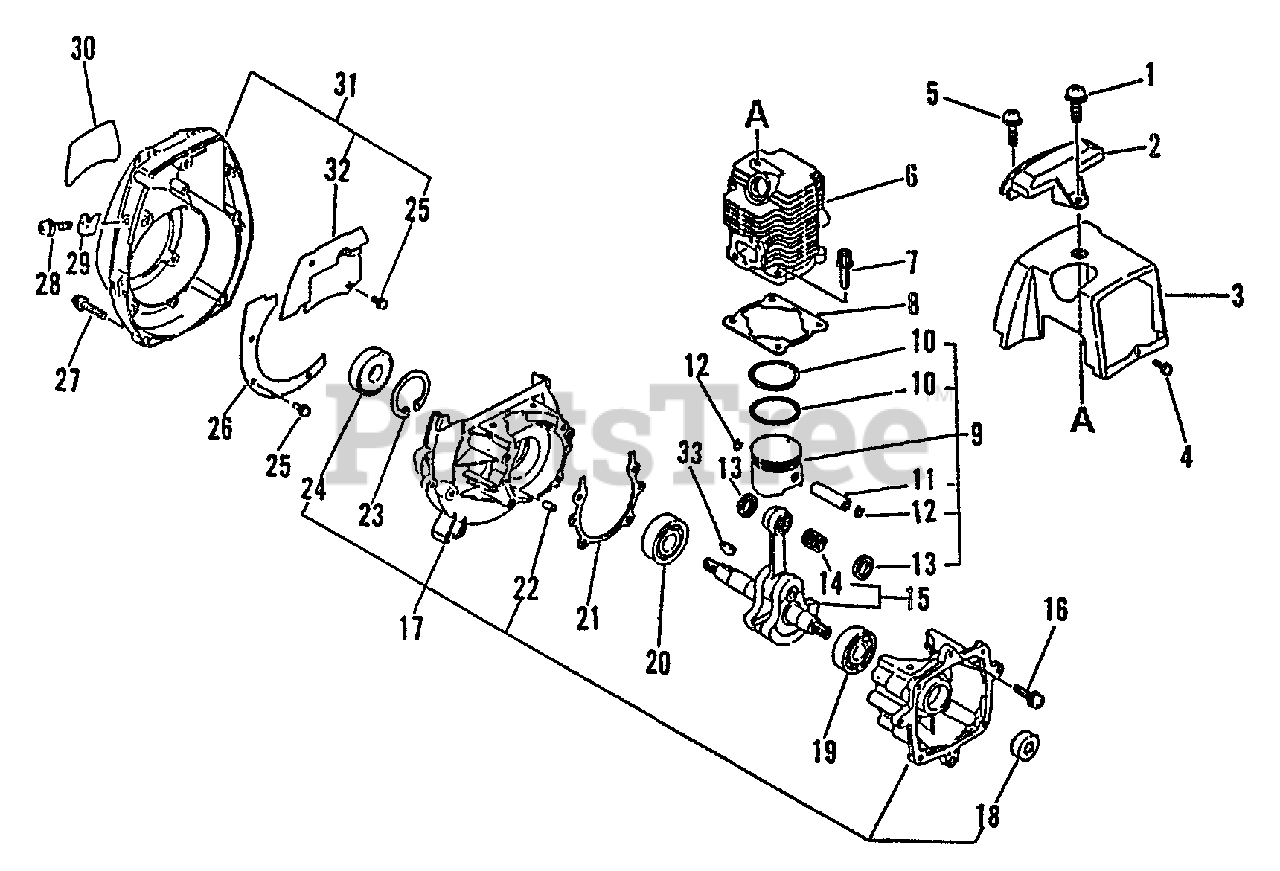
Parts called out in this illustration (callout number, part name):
1	SCREW 5×16
2	GUARD, TOP
3	COVER, ENGINE
4	SCREW 4×10
5	SCREW 4×14
6	CYLINDER
7	BOLT 5×20
8	GASKET, CYLINDER
9	PISTON KIT
10	RING, PISTON
11	PIN, PISTON 8
12	RING, SNAP
13	WASHER, THRUST
14	BEARING, NEEDLE
15	CRANKSHAFT ASSY
16	SCREW 5×25
17	CRANKCASE KIT
18	SEAL, OIL 12
19	BEARING, BALL 6001
20	BEARING, BALL - 6201 C3
21	GASKET, CRANKCASE
22	PIN, LOCATING 4
23	RING, SNAP Ø32
24	SEAL, OIL 12
25	SCREW 4×8
26	PLATE, GUIDE
27	BOLT 4×20
28	SCREW 4×10
29	HOLDER, CABLE
30	LABEL, LST-2400
31	FAN CASE ASSY
32	PLATE, GUIDE
